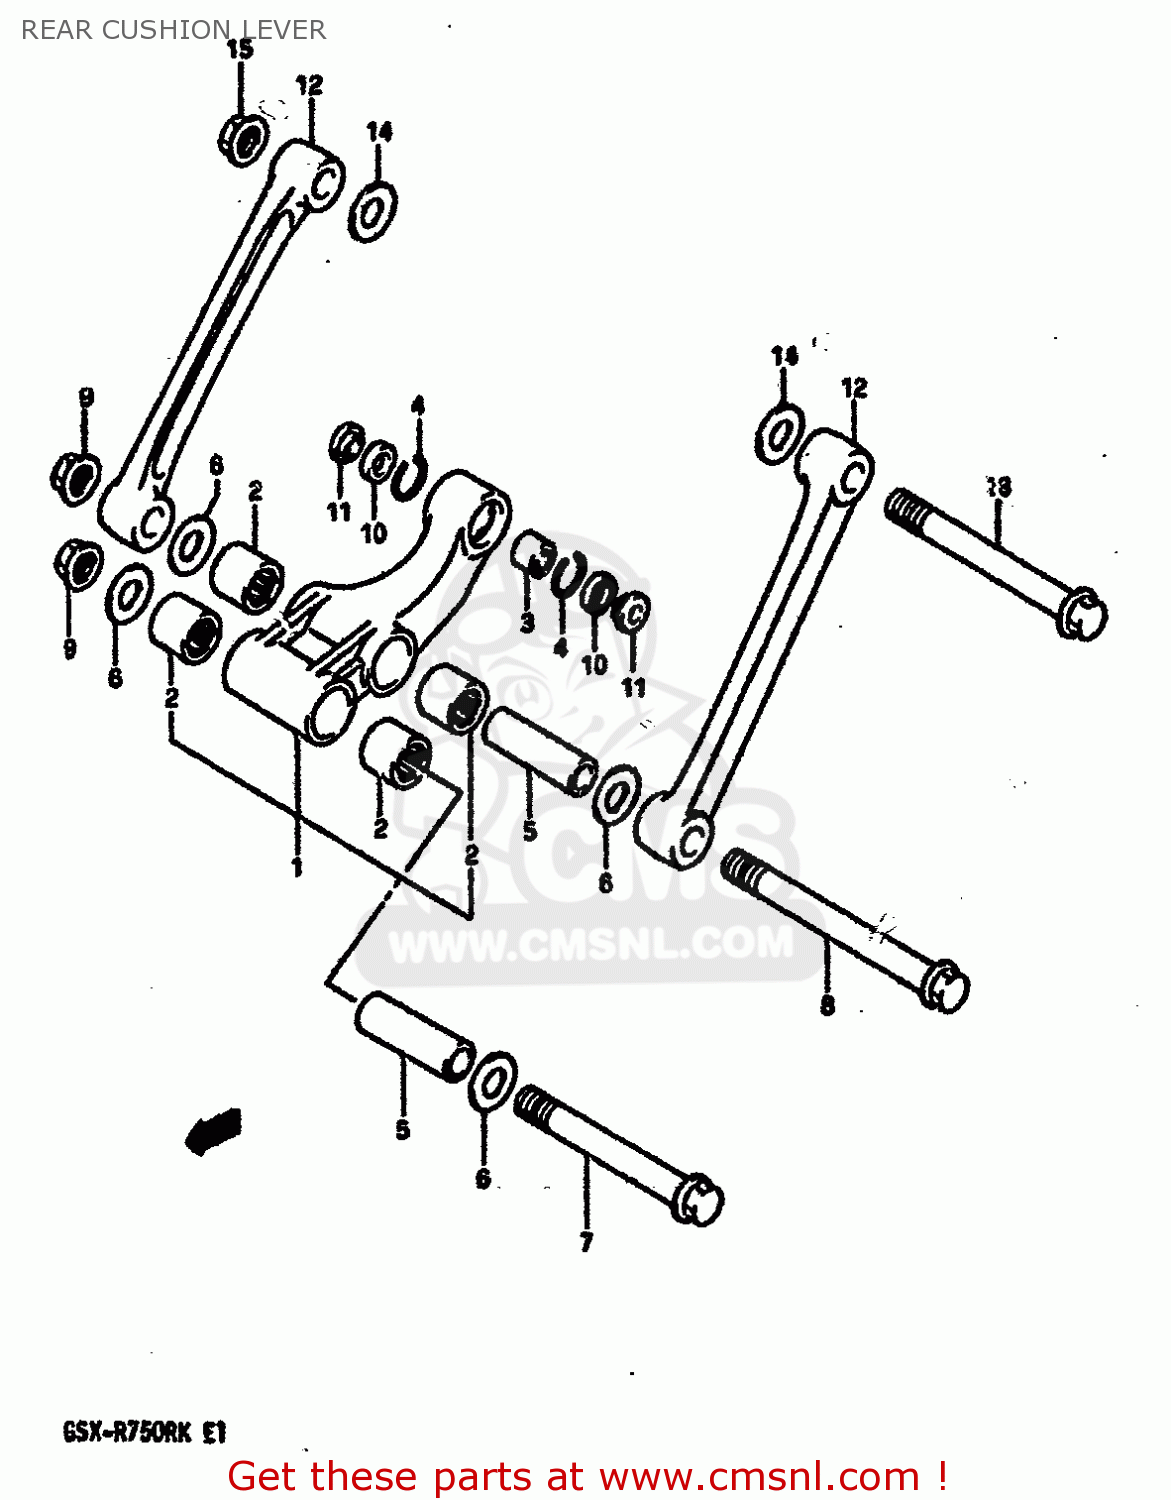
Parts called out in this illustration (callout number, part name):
1	LEVER SET,REAR CUSHION
2	BEARING(20X27X23.5)
3	BEARING,RR CUSHION LEVER
4	RING,STOPPER
5	SPACER,RR CUSHION LEVER
6	WASHER
7	SHAFT,RR CUSHION LEVER FR
8	SHAFT,RR CUSHION ROD
9	NUT
10	DUST SEAL,RR CUSHION LEVER RR
11	SPACER
12	ROD,REAR CUSHION
13	SHAFT,RR CUSHION ROD
14	WASHER
15	NUT
